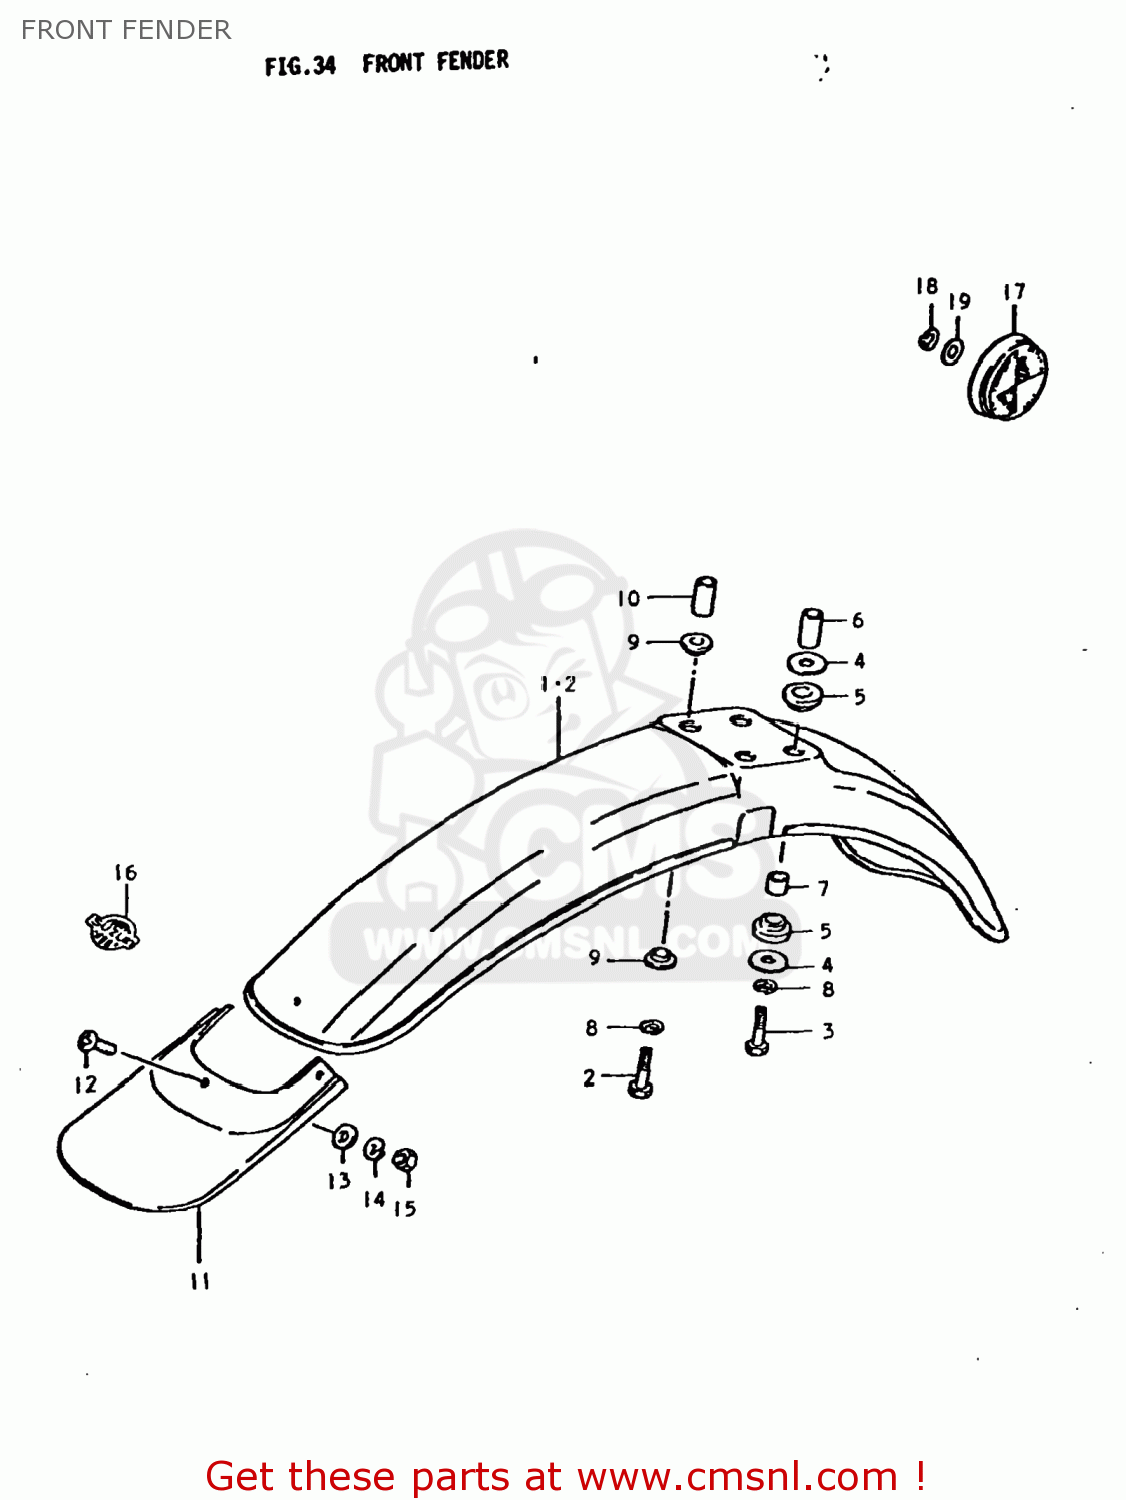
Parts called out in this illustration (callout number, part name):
1	FENDER,FRONT
2	FENDER,FRONT
3	BOLT
4	WASHER (6.5X20X1.2)
5	CUSHION
6	SPACER
7	SPACER (6.8X10X10)
8	LOCK WASHER
9	SPACER
10	SPACER
11	MUD FLAP,FRONT FENDER
12	SCREW
13	WASHER
14	LOCK WASHER
15	NUT
17	REFLEX REFLECTOR,FR
18	LOCK WASHER
19	WASHER
